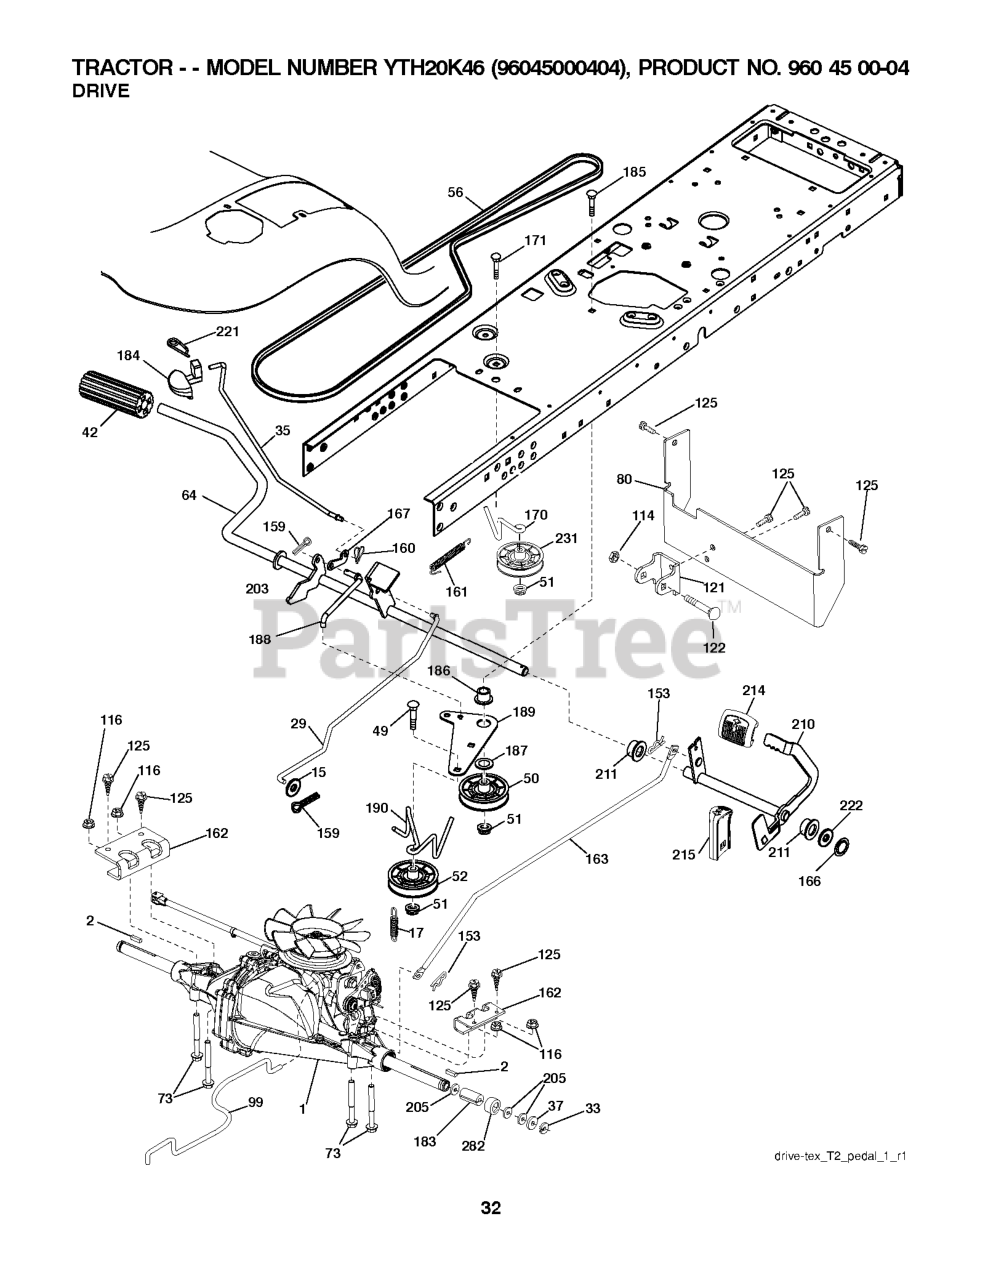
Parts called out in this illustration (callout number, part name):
2	SQUARE KEY
15	WASHER
17	SPRING.BRAKE.HG3000/3500
26	SPRING.RETURN.CRUISE
29	ROD.BRAKE.T2.TEX
35	ROD.BRAKE.PARKING.GT.H
42	PEDAL COVER T
50	IDLER.FLAT.910.OFFSET
51	NUT LOCK FLG 3/8-16 UNC
52	IDLER.V-GROOVE.910.OFFSET
64	SHAFT.ASM.PEDAL.BRK.CNTR
80	RP.STRAP.TORQUE.FS.T2
92	BOLT
99	ROD.ASM.BYPASS.SPRING.T2.FS
114	NUT LOCK HEX FLANGE 5/16-18
116	NUT LOCK HEX FLANGE 5/16-18
121	BRACKET STRAP TORQUE
122	BOLT.5/16-18X2.5
125	SCREW
143	Screw 5/16-18 x 1/2 Hex, Self Tapping 5/16-18 x 1/2
153	RETAINER M
159	COTTER PIN
160	RETAINER CLIP
161	SPRING, RETURN LT
162	ADAPTER.TRANSAXLE.T2.TLT.DRWBR
163	ROD.CONTROL.PCH.T2.TEX
166	NUT.PUSH.625.2006
167	LATCH.BRAKE.SPRING
170	KEEPER.V-IDLER.CENTER.
183	SPACER, AXLE PVST
184	HANDLE.PARKG.BRK.HUSQ X667
186	SPACER.RETAINER
187	WASHER 12/32X2X10GA
188	RP.LINK.CLUTCH.GROUND.DRIVE
189	BELLCRANK.GROUND.DRIVE.TEX.
190	KEEPER.BELLCRANK.DRIVE
206	BRKT.MOUNT.LATCH.CRUIS
207	LATCH.CONTROL.CRUISE
208	GEAR.SECTOR.CONTROL.CR
209	ROD.CONTROL.CRUISE.GT.
210	ROCKER.ASM.PEDAL.CONTR
211	BEARING.NYLON
213	KNOB.CONTROL.CRUSIE.HU
214	PEDAL.FORWARD.TEX.GT.4
215	PEDAL.REVERSE.TEX.GT.4
216	BRACKET.PULLEY.IDLER.W/TEX
221	RETAINER.SPRING.CLIP.H
222	WASHER 21/32 X 1-1/4 X 10 GA.
231	IDLER.V-GROOVE.1.688.OFFSET
